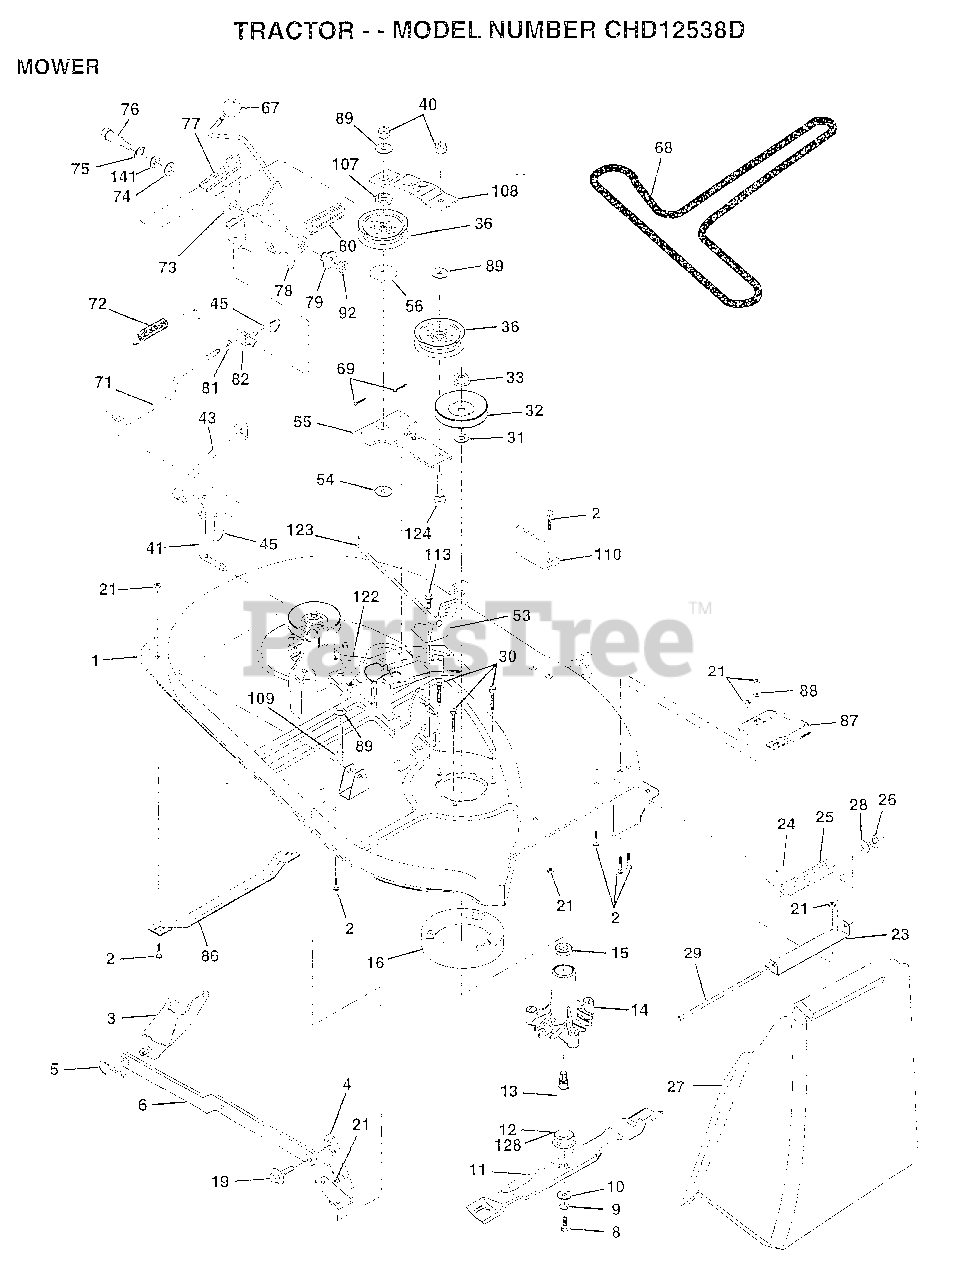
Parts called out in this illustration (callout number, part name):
2	BOLT
3	BRKT ASM SWAY BAR
4	BRKT DECK SW BAR
8	BLADE BOLT
10	WASHER.HARD.BLADE
11	"BLADE.38"" HIPERF"
12	BEARING.BALL
14	HSG ASM MANDREL
15	BEARING
16	STRIPPER RND MWR
19	BOLT SHD 5/16-18
23	BRKT DEFLECTOR
24	CAP-SLEEVE LT
25	SPRING TORSION
26	NUT PUSH M
27	DEFLECTOR-SHLD T
28	WASHER
29	ROD-HINGE T
30	"SCREW-THD ROLL,WA"
31	WASHER
32	PULLEY.MANDREL.38
36	FLAT IDLER PULLEY
41	PIVOT ROD
43	CLUTCH ROD SECOND
45	RETAINER M
53	BRAKE ASM
54	HARDENED WASHER
55	IDLER ARM ASSY
56	SPACER RETAINER
67	KNOB.RD.7/16-14
68	BELT.V.T-PATH
71	ROD CLUTCH 38/42
72	RETURN SPRING
73	CLUTCH ARM SECOND
74	WASHER
75	RING
76	SHOULDER BOLT
77	SPRING KEEPER
78	LEVER.ASM.CLUTCH
79	BUSHING
80	SPRING.CLUTCH.MWR
81	NUT
82	TRUNION ADJ
86	RUNNER-LH M
87	RUNNER RH
88	WASHER M
89	WASHER GT
92	NUT
107	RETAINER SPACER
108	IDLER ARM STIFF
109	BOLT
110	UPSTOP DECK FT 38
113	SCREW
122	BRAKE ROD LH
123	BRAKE ROD RH
124	BOLT
128	WASHER.FELT.
141	WASHER .T
